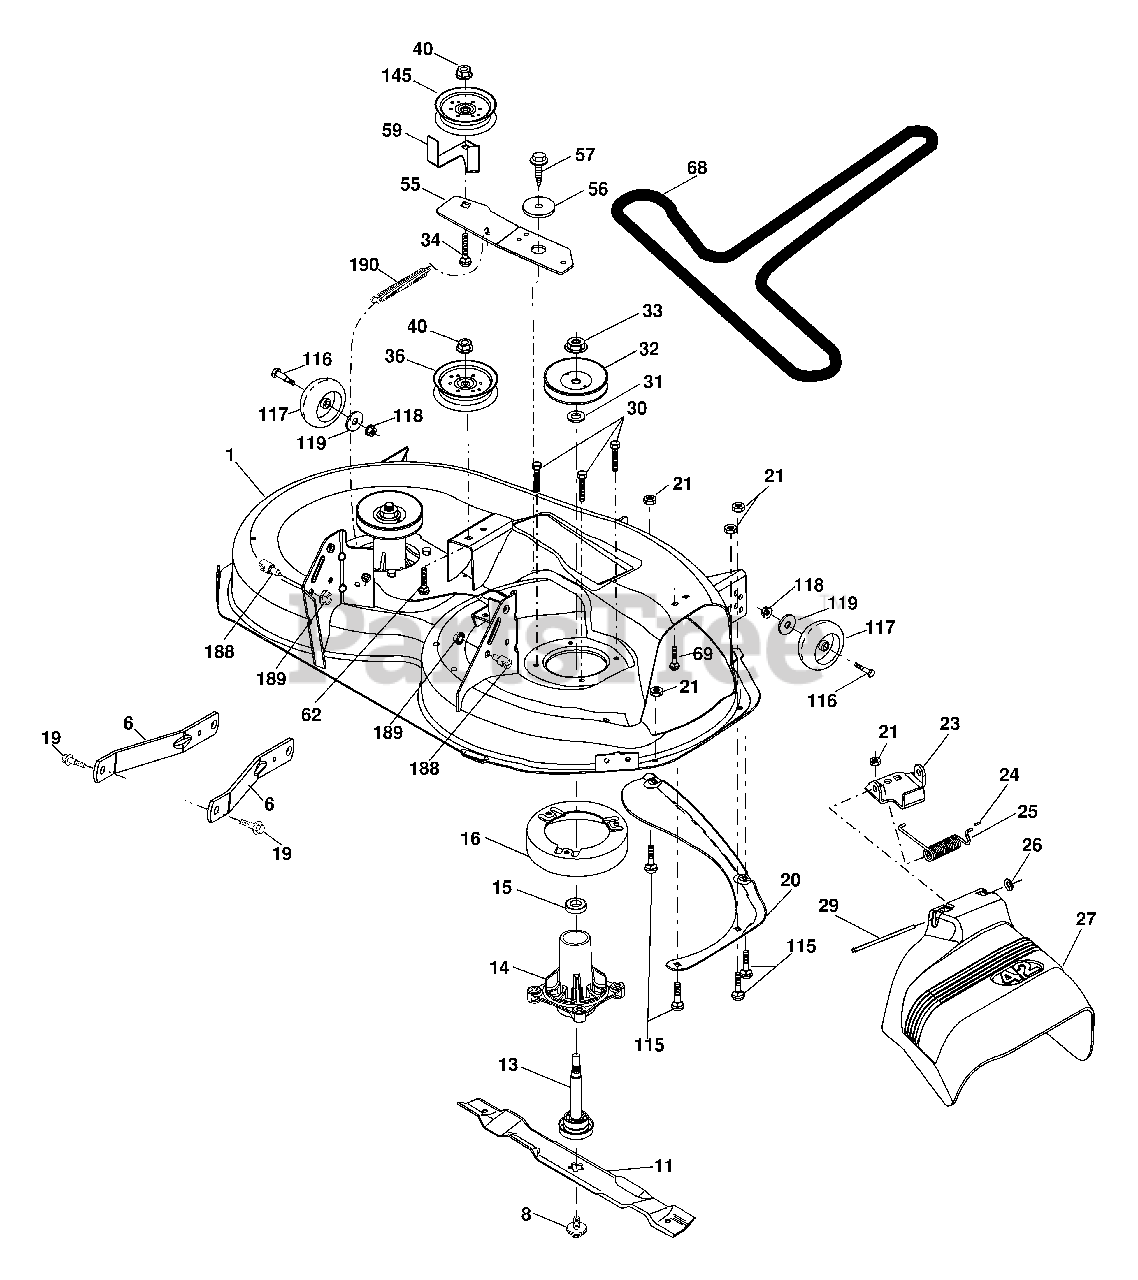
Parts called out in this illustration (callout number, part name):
1	Mower Housing
6	Arm Suspension
8	Bolt/Washer asm 7/16-20 unf
11	Blade, 42" Hi-Lift
11	Blade, 42" Mulching Std
11	Blade, 42" Mulching Premium
13	Shaft Assembly, Mandrel
14	Housing, Mandrel
15	Bearing, Ball, Mandrel
16	Stripper, Mower Deck
19	Bolt, Shoulder
20	Baffle, Vortex
21	Nut, Crownlock 5/16-18 unc
23	Bracket, Deflector
24	Cap, Sleeve
25	Spring, Torsion, Deflector
27	Shield, Deflector
29	Rod, Hinge
30	Screw Thdrol Rolling Wsh Hd
31	Washer, Spacer
32	Pulley, Mandrel
33	Nut, Toplock, Flanged
34	Bolt Carr Sh. 3/8-16 x 1-1/2 Gr. 5
36	Pulley, Idler, Flat
40	Nut, Lock Flg. 3/8-16 unc
55	Arm, Idler
56	Spacer, Retainer
57	Screw 3/8-16 x 1
59	Guard, Tuv Idler
62	Bolt Rd Hd Sq Nk 3/8-16 unc x 2
69	Bolt
115	Bolt Carr. 5/16-18 x 5/8
116	Bolt, Shoulder
117	Wheel, Gauge
118	Nut, Crownlock 3/8-1
119	Washer 13/32 x 7/8 x 14 Ga.
145	Pulley Idler
188	Stud Fastener
189	Nut Lock Hex Flange
190	Spring Mower Drive Electric
